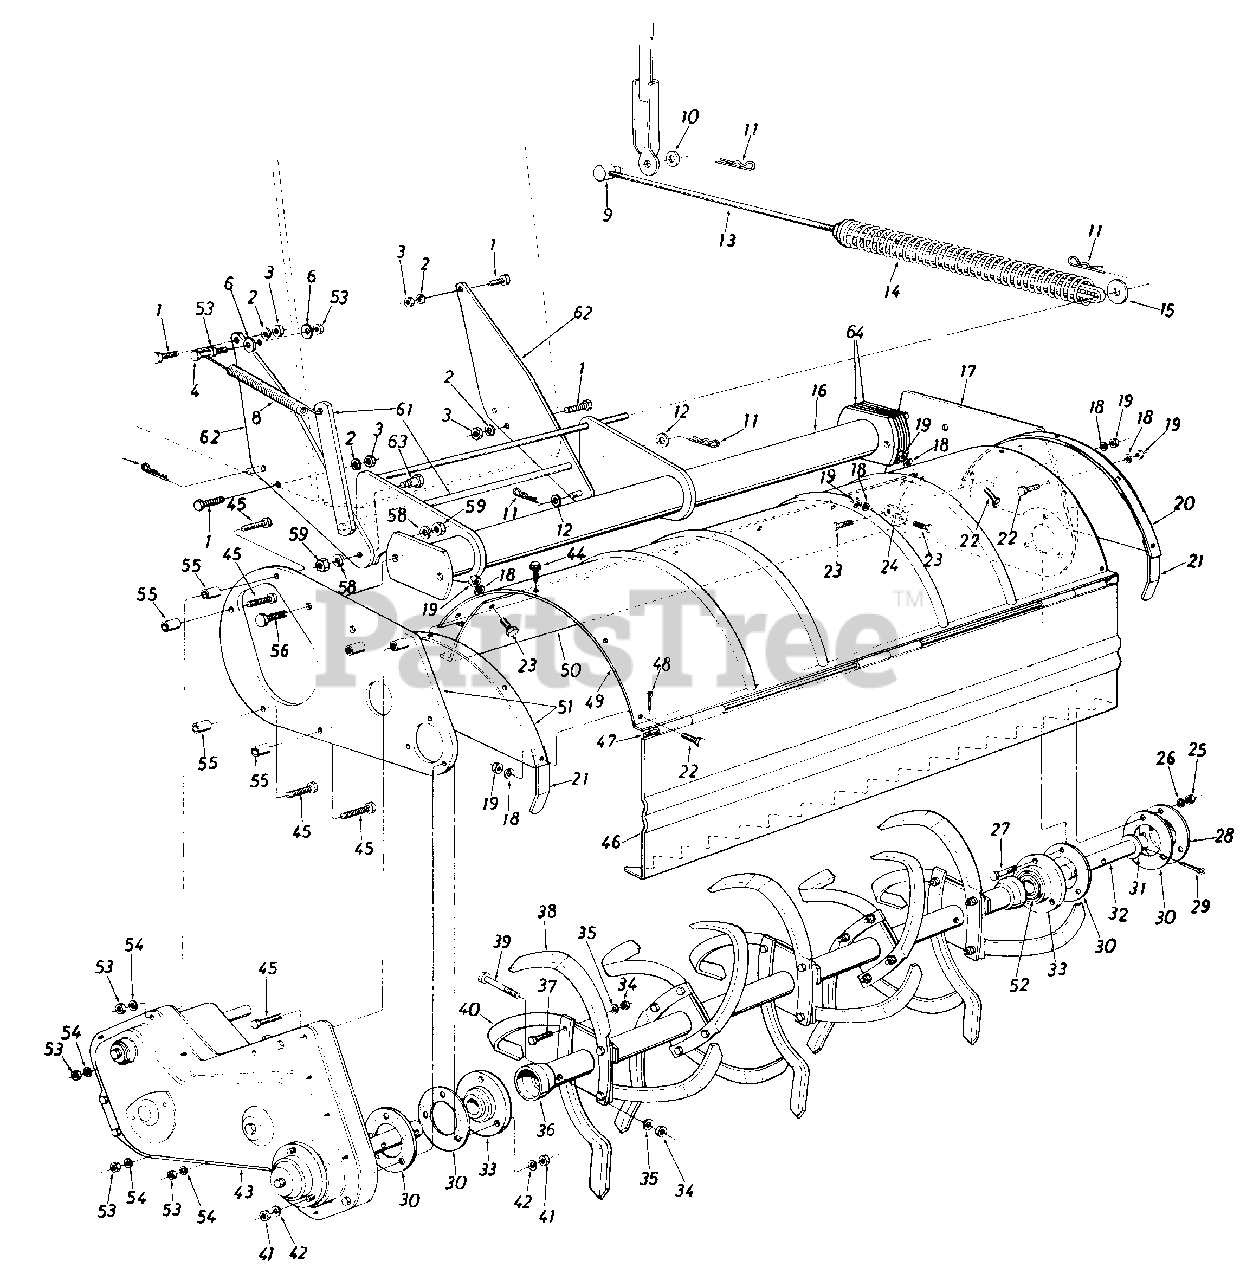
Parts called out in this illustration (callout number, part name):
1	Hex Bolt 3/8-24 x .88" Lg.
2	L.-Wash. 3/8" I.D. Heavy Duty
3	Hex Nut 3/8-24 Thd.*
4	Hex Bolt 1/4-20 x 1.25" Lg.*
6	Bell-Wash 1/4" I.D.*
8	Extension Spring .56" O.D. x 7.75" Lg.
9	Adjustment Ferrule 1/2-13 Thd.
10	Fl.-Wash. .640" I.D. x 1.24" O.D. x .060
11	Intern. Cotter Pin 1/2" Dia.
12	Fl.-Wash. .510" I.D. x 1.0" O.D. x .060
13	Lift Rod Ass'y. 39.0" Lg.
14	Compression Spring 1.50" O.D. x 15.0" Lg.
15	Fl.-Wash. .51" I.D. x 1.50" O.D. x .075
16	Pivot Bracket Assembly
19	Hex Nut 5/16-24 Thd.*
23	Hex Bolt 5/16-24 x .62" Lg.
24	Chute Pivot Bracket
25	Hex Cent. L.-Nut 5/16-18 Thd.
26	L.-Wash. 5/16" I.D.*
27	Hex Bolt 5/16-18 x 1.0" Lg. (Grade 5)
30	Gasket for Brg. Housing
31	Fl.-Wash. 1.25" I.D. x 2.00" O.D. x .06
32	Tine Shaft R.D. 1.25" Dia. x 6.25" Lg.
33	Bearing Housing w/Bearing
34	Hex Nut 3/8-24 Thd.*
35	L.-Wash. 3/8" I.D. Heavy Duty
41	Hex Cent. L.-Nut 5/16-18 Thd.
42	L.-Wash. 5/16" I.D.*
43	Chain Case Ass'y. Comp.
44	Hex Wash. TT Tap. Scr. 5/16-18 x .62" Lg.
45	Hex Bolt 1/4-20 x 2.75" Lg.*
48	Cotter Pin 1/8" Dia. x 1.00 Lg.
53	Hex Nut 1/4-20 Thd.
54	L.-Wash. 1/4" I.D.
55	Spscer.28" I.D. x .62" O.D. x .90" Lg.
56	Hex Bolt 1/2-20 x 1.5" Lg.
58	L.-Wash. 1/2" I.D.
59	Hex Jam Nut 1/2-20 Thd.
61	Idler Bracket Support Arm Ass'y.
64	Support Plate
